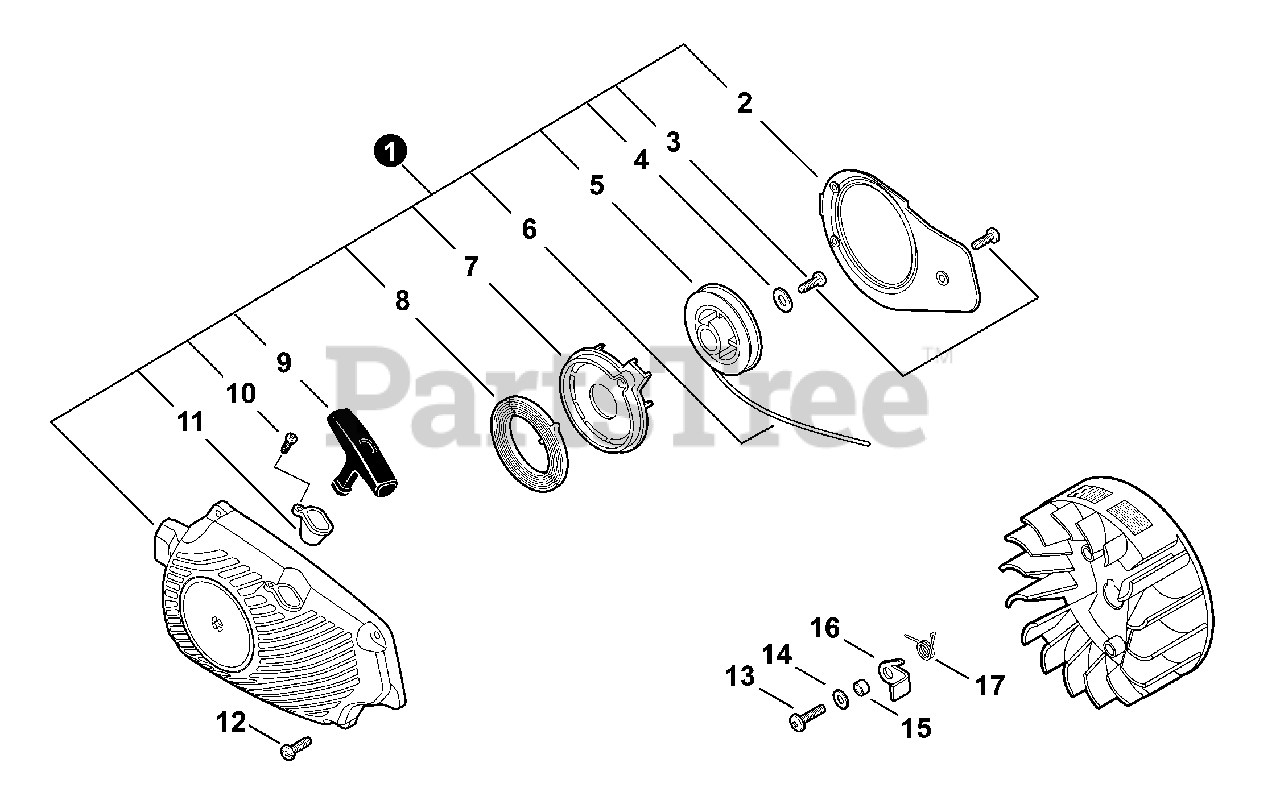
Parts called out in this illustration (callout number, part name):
1	STARTER ASSY, RECOIL
2	PLATE, GUIDE
3	SCREW 4×14
4	WASHER 4.1×15.5×1T
5	REEL, ROPE
6	ROPE, STARTER 3.0×850
7	PLATE, STARTER
8	SPRING, RECOIL
9	GRIP, STARTER
10	SCREW 3×14
11	GUIDE, ROPE
12	SCREW 4×16
13	SCREW 5×12
14	WASHER 5.5×12×0.8
15	SPACER 5.2×8×2.1
17	SPRING, TORSION
